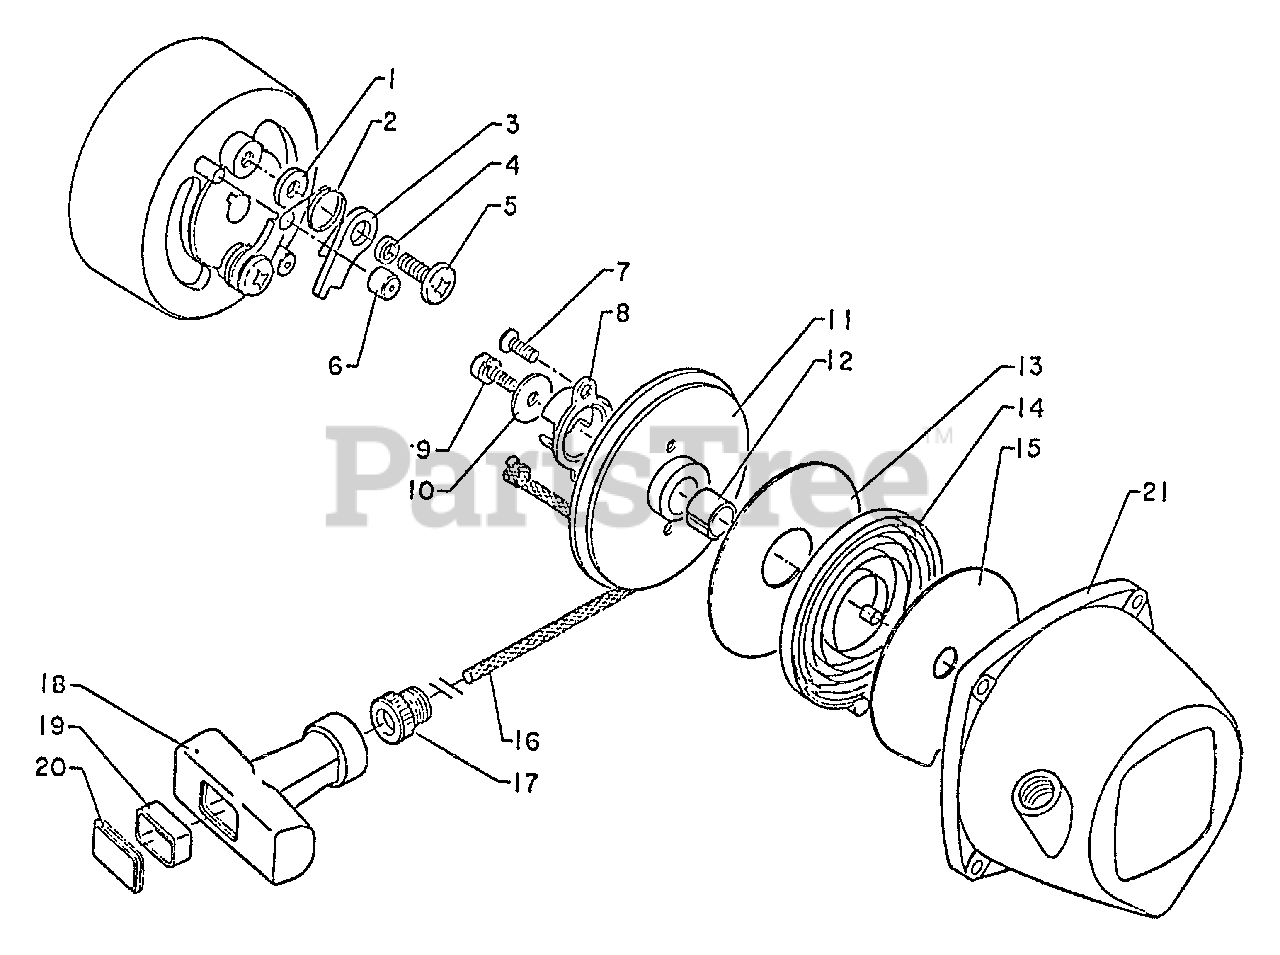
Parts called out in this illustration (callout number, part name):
1	WASHER
2	SPRING, RETURN
3	PAWL, STARTER
5	SCREW
7	SCREW - 4X8
8	CATCHER, PAWL
9	SCREW - 4X8
9	LOCKWASHER - 4
11	REEL, ROPE
13	PLATE, STARTER
14	SPRING, REWIND
15	PLATE, STARTER
16	ROPE, STARTER - 3.5X850
17	GUIDE, ROPE
18	GRIP, STARTER
19	RING, RETAINING
21	CASE, STARTER
